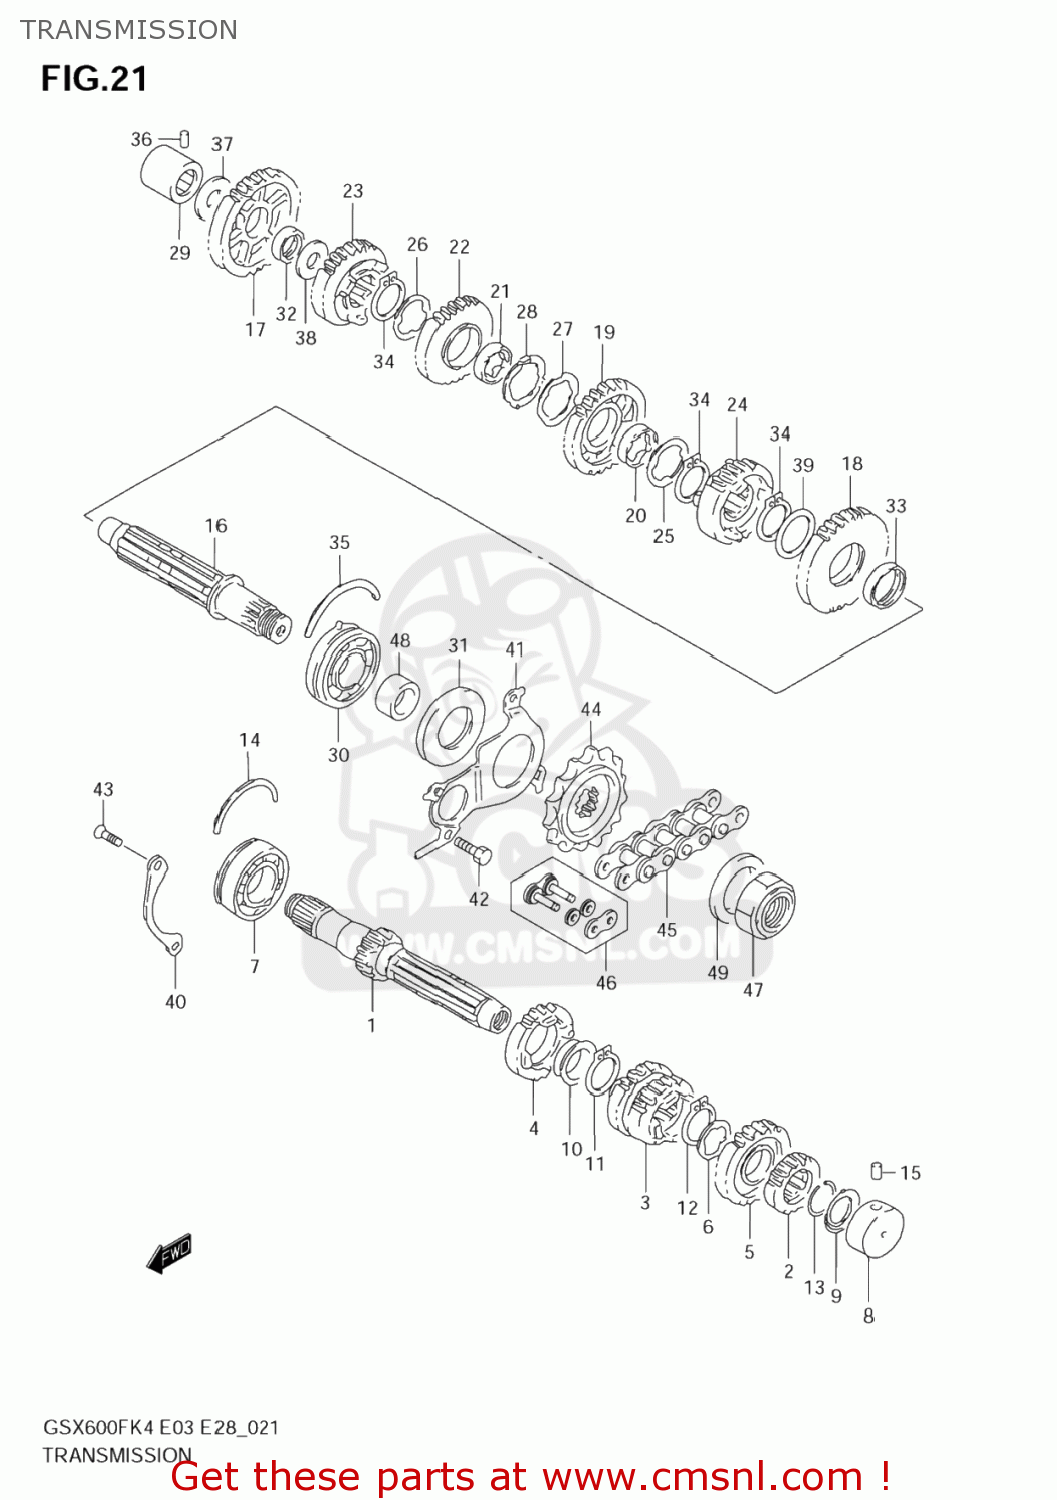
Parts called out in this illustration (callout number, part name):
1	SHAFT,COUNTER(NT:12)
2	GEAR,2ND DRIVE(NT:16)
3	GEAR,3RD & 4TH DRIVE(NT:17/20)
4	GEAR,5TH DRIVE(NT:22)
5	GEAR,6TH DRIVE(NT:21)
6	WASHER,LOCK
7	BEARING(25X62X17)
8	BEARING(20X34X17.5)
9	SEAL,OIL(20X31.2X2.7)
10	BUSH
11	RING,SNAP
12	RING,SNAP
13	CIRCLIP
14	C RING
15	PIN
16	SHAFT,DRIVE
17	GEAR,1ST DRIVEN(NT:37)
18	GEAR,2ND DRIVEN(NT:33)
19	GEAR,3RD DRIVEN(NT:28)
20	BUSH
21	BUSH
22	GEAR,4TH DRIVEN(NT:28)
23	GEAR,5TH DRIVEN(NT:27)
24	GEAR,6TH DRIVEN(NT:23)
25	WASHER,LOCK
26	WASHER,LOCK
27	WASHER,LOCK
28	WASHER
29	BEARING(20X34X20)
30	BEARING(25X62X21.6)
31	SEAL,OIL(34X62X6)
32	BUSH(22X26X9)
33	BUSH(28X32X9.5)
34	CIRCLIP
35	C RING
36	PIN
37	SHIM(20X34X1)
38	SHIM(22X34X1)
39	SHIM(28X38X1)
40	RETAINER,CNTR SHAFT BEARING
41	RETAINER,DRIVE SHAFT OIL SEAL
42	BOLT
43	SCREW(6X12)
44	SPROCKET,ENGINE(NT:15)
45	CHAIN,DRIVE(118LE)
46	JOINT SET,CHAIN
47	NUT
48	SPACER(25X34X17.5)
49	SHIM(25X40X1.5)
